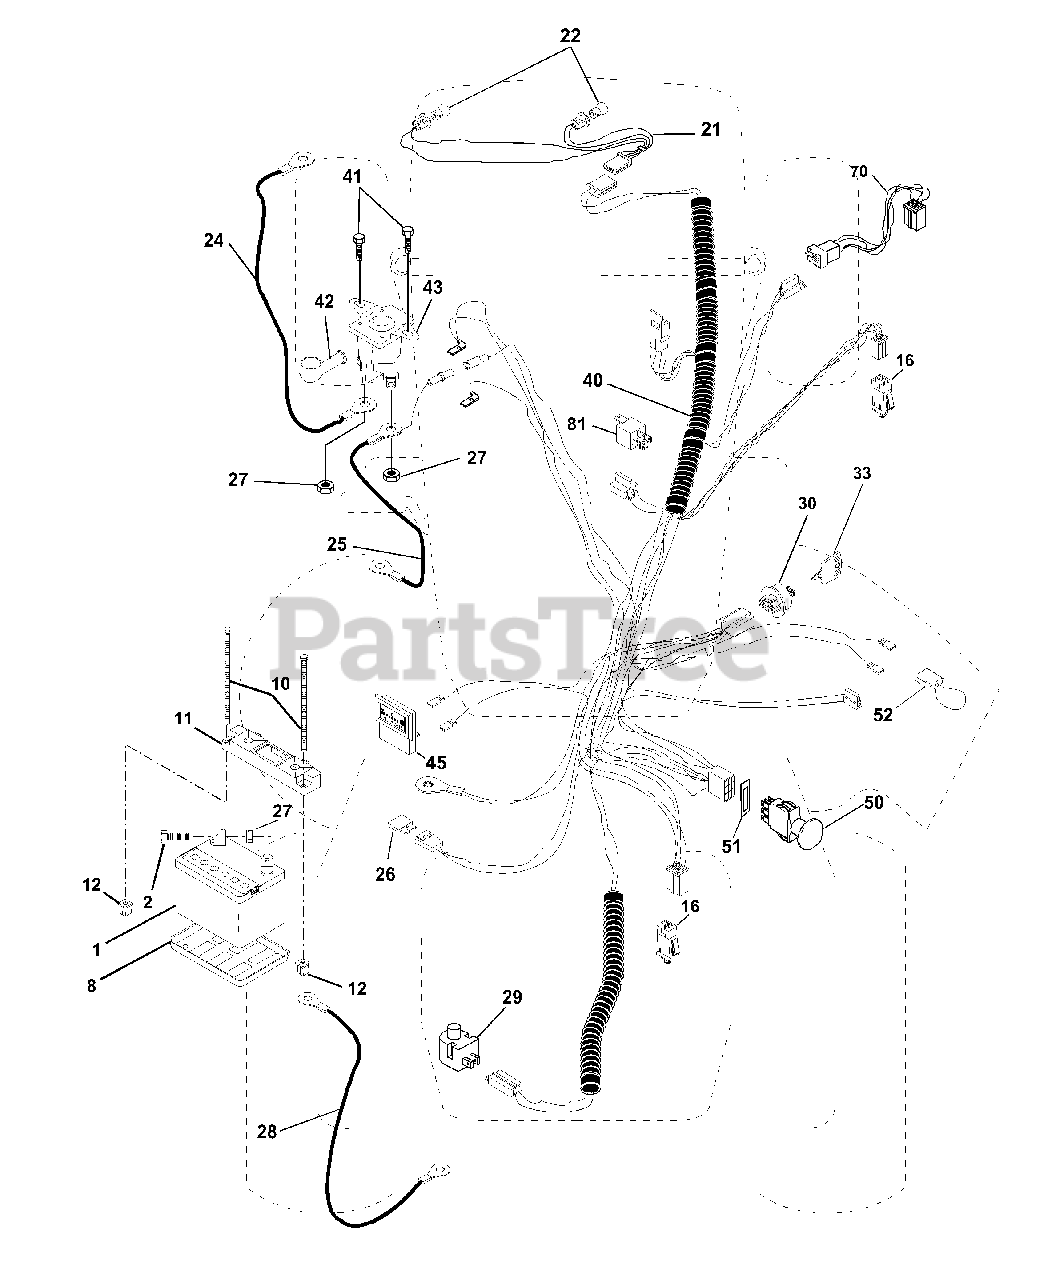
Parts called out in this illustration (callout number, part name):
1	Battery
2	Bolt Hex Head 1/4-20 x 3/4
8	Tray, Battery
10	Bolt, Battery Front 1/4-20 x 7.5 Zinc
11	Holddown Battery Front Mount
12	Nut, Push Nylon 1.4" Battery Front
16	Switch Interlock Push-In
21	Harness Socket Light w/4152J
22	Bulb Light
24	Cable, Battery
25	Cable, Battery
26	Fuse
27	Nut Keps Hex 1/4-20
28	Cable,Ground
29	Switch, Plunger Normal Op Olive
30	Switch, Ign
33	Key
40	Harness Ign.
41	Screw 1/4-20 x 1/2
42	Cover, Terminal Red
43	Solenoid
45	Ammeter
50	Switch, PTO
51	Ring Retainer PTO
52	Protection, Wire, Loop
70	Harness Engine
81	Relay Asm.
